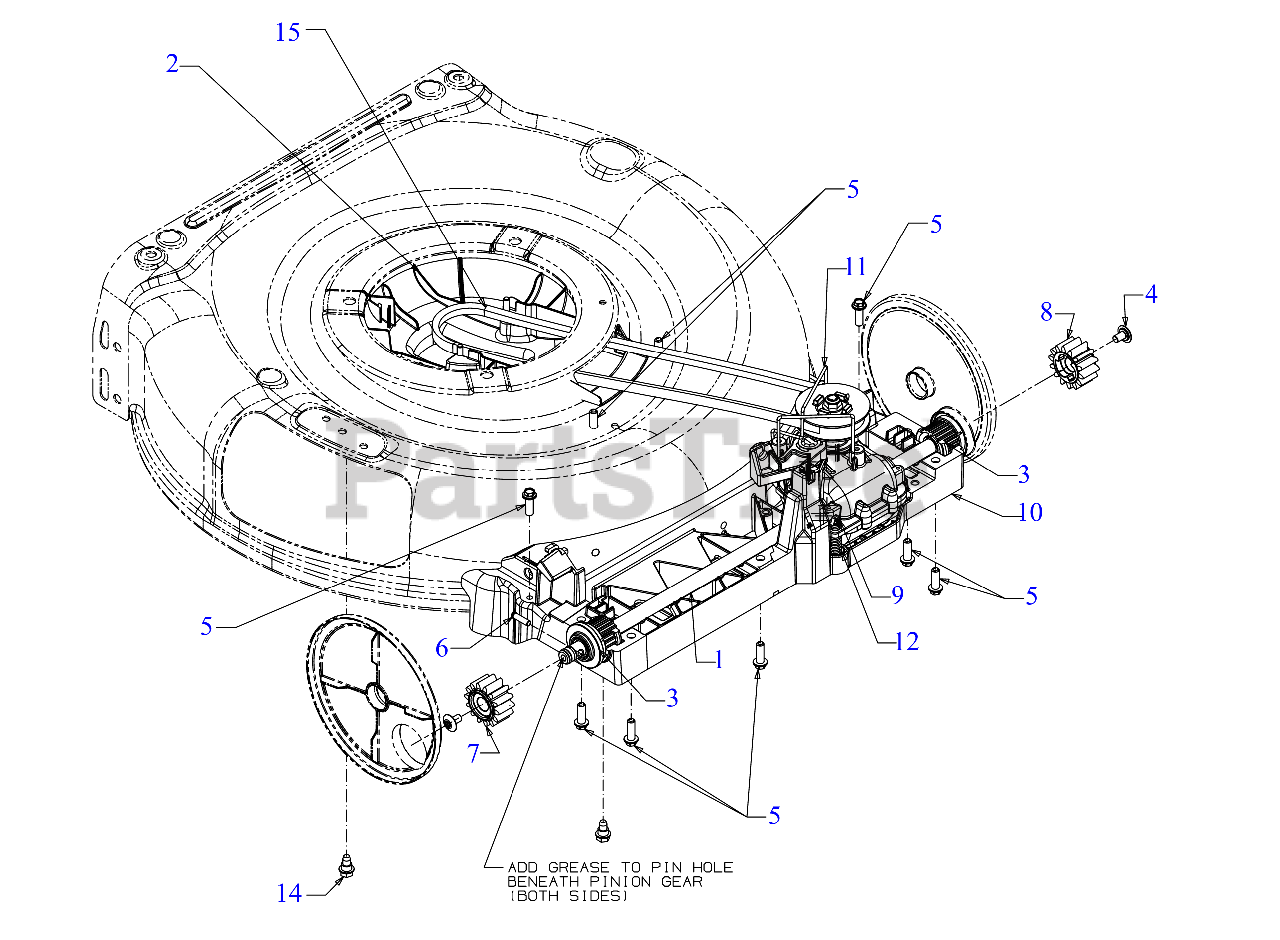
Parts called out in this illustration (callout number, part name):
1	FORWARD TRANSMISSION ASSEMBLY
2	ENGINE BAFFLE ASSEMBLY
3	BEARING ASSEMBLY
4	SCREW 1/4-20 x .39
5	SCREW 1/4 x .750
7	SPUR GEAR 14T (RH)
8	SPUR GEAR 14T (LH)
9	SPRING COMPRESSION
10	LOWER TRAY
11	TRANSMISSION WIRE
12	COMPRESSION SPRING
14	SHOULDER SCREW 1/4-20 x .50
15	V-BELT 3L 34.18
